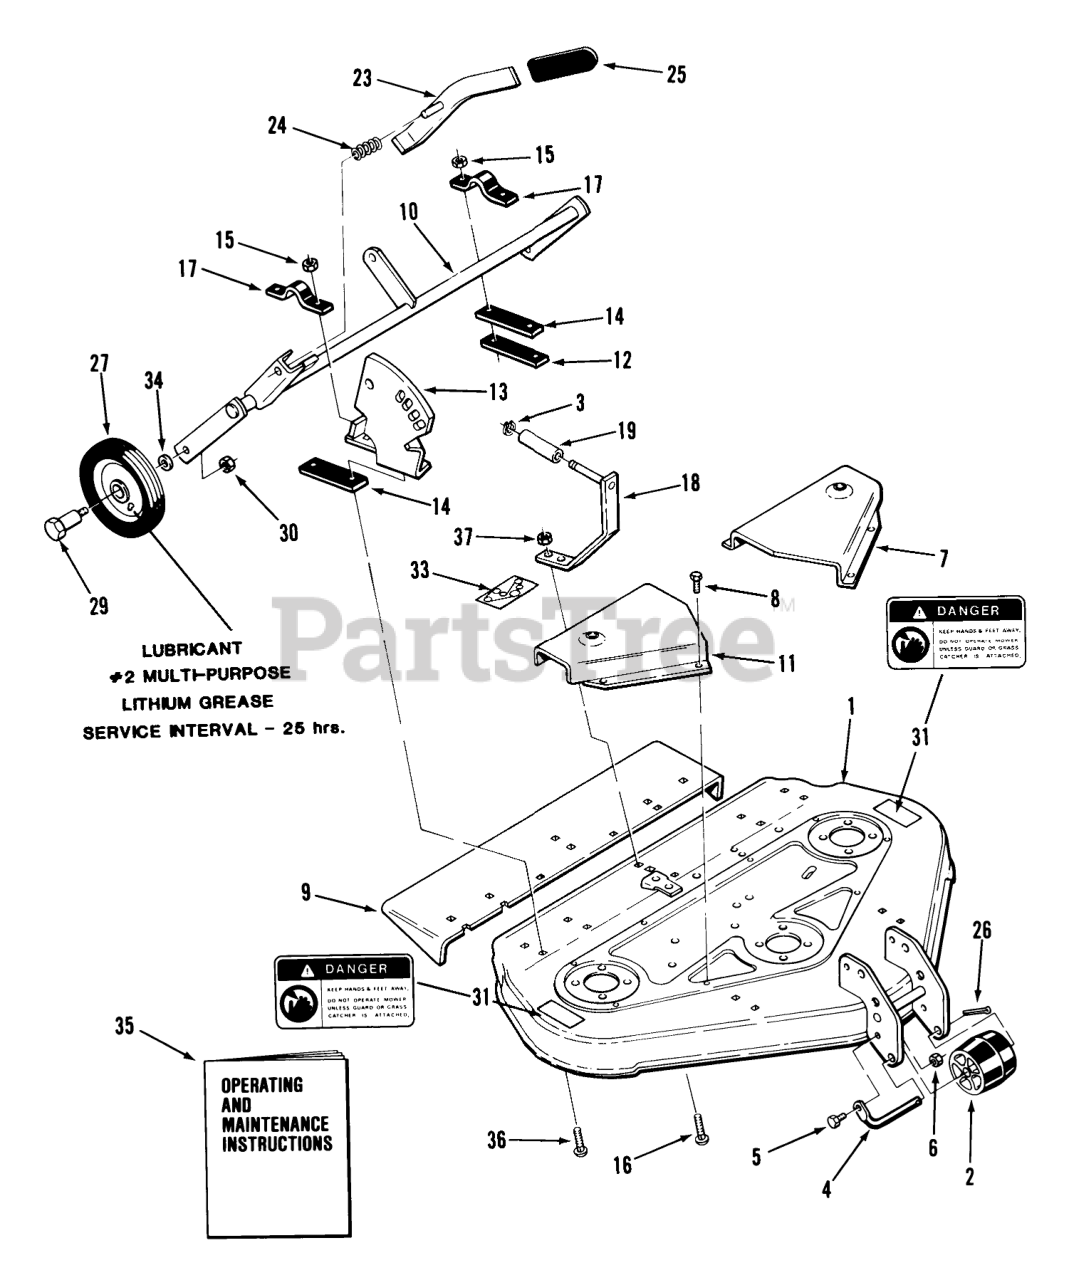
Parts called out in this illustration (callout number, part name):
1	Mower Deck
2	Roller
3	Snap Ring
4	ROLLER-SHAFT
5	H H C S
6	Nut
7	Cover-Belt
8	SCREW -4
9	Chute Extension
10	ASSY GAGE WHEEL S R
11	Belt Cover RH
12	Bar
13	QUADRANT R
14	STRAP 1/16 B
15	Nut
16	Bolt-Carriage
18	BRACKET ASSY R
19	SPACER
23	Lever
24	SPRING-COMPRESSION
26	Cotter Pin
27	WHEEL
29	BOLT-SHOULDER
30	Nut
31	Danger Decal
33	DECAL-HEIGHT BELT
34	WASHER
35	Operating & Maintenance Instructions
36	Bolt
37	NUT
